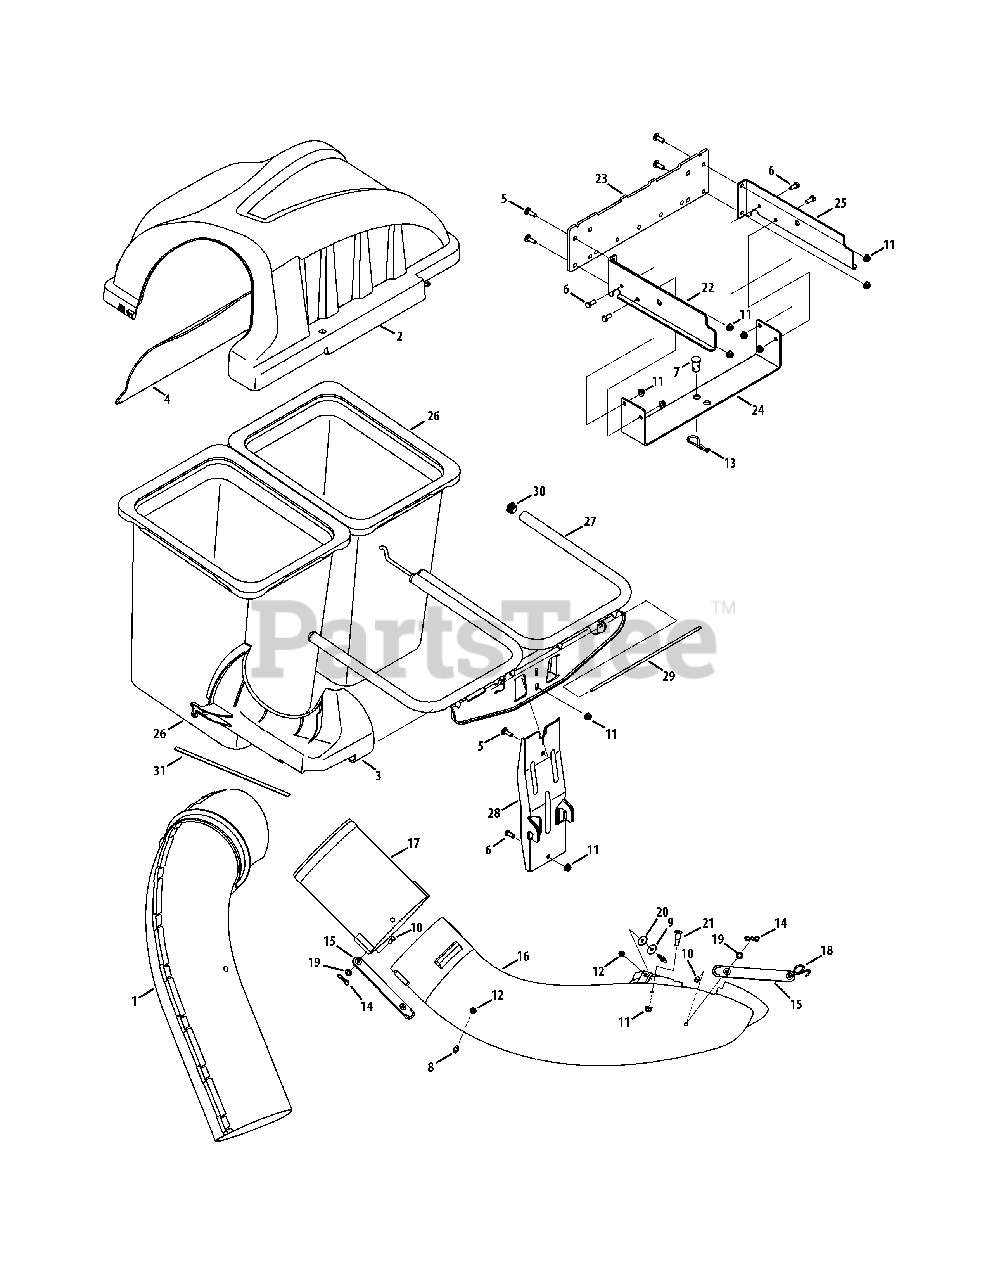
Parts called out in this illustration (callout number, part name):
1	Upper Chute Assembly
2	Double Bagger Cover Assembly
3	Upper Chute Support
4	Bagger Cover Screen
5	Carriage Screw, 5/16-18 x 1.00"
6	Hex Head Screw, 5/16-18 x .75"
7	Clevis Pin, .62" Dia.
8	Grass-catcher Pin, 1/4-20
9	Attachment Pin, 1/4 x 0.66 Lg.
10	Clevis Pin, 5/16 x .75 Lg.
11	Flange Lock Nut, 5/16-18
12	Flange Lock Nut, 1/4-20
13	Internal Cotter Pin, .148 x 3.00
14	Bow-Tie Cotter Pin, 72
15	Chute Strap, 6.00 Lg.
16	Bagger Discharge Chute, Elbow
17	Bagger Chute Adapter, 7 In.
18	Torsion Spring Hook
19	Flat Washer, .344 x .62 x .033
20	Flat Washer, .265 x 1.0 x .030
21	Shoulder Screw, .437 x .54
22	Mounting Bracket, RH
23	Universal Mounting Bracket
24	Universal Bracket Support, i-Series
25	Mounting Bracket, LH
26	Grass-bag Assembly
29	Cover Hinge Pin
31	Foam Strip
